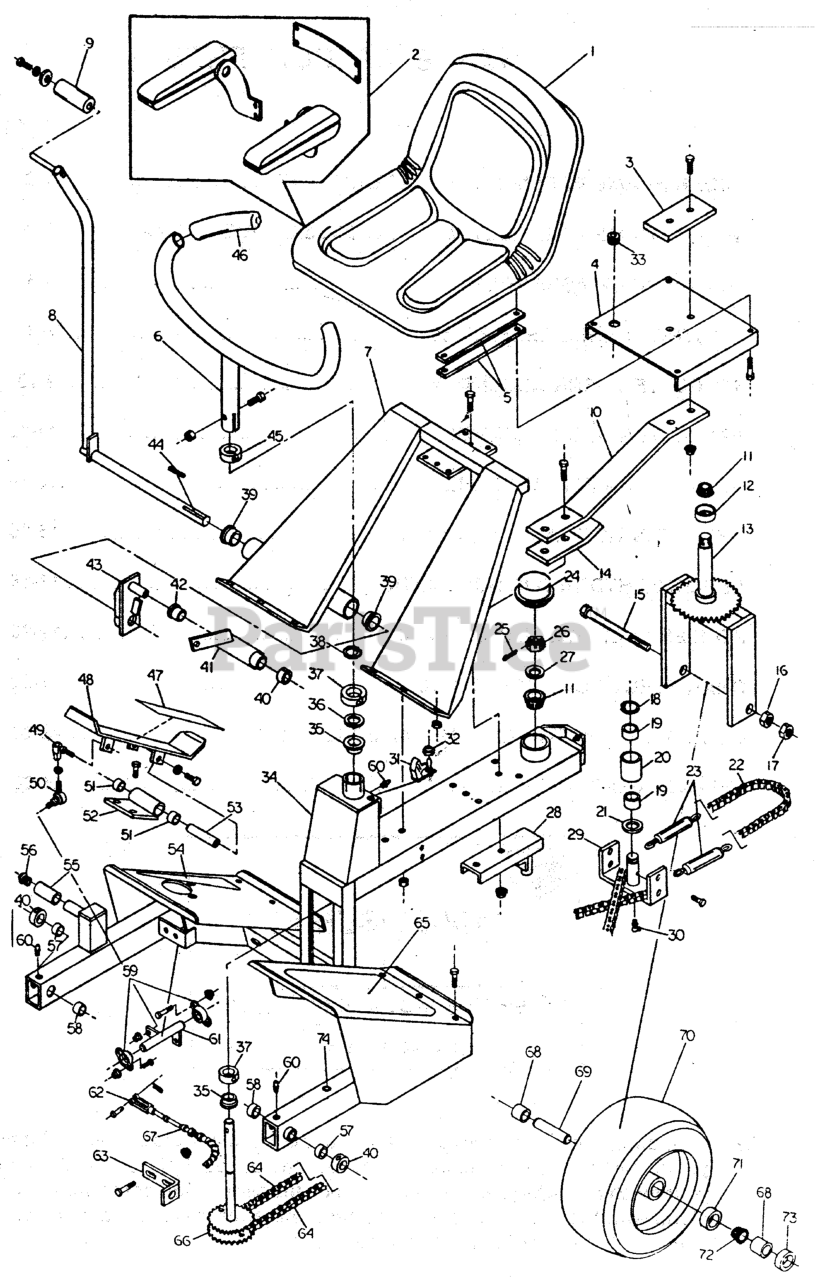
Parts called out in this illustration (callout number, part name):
2	Arm Rest Kit
2	Arm Rest (Left/Right Interchangeable)
3	SUPPORT, Seat Plate
4	Seat Plate
5	Seat Plate Spacer
6	STEERING HANDLE
7	Rider Frame Support
8	LIFT HANDLE
9	Plastic Handle
10	SEAT SPRING
11	BEARING, Tapered Roller
12	BEARING CUP
13	MOUNT, Steering Tire
14	SUPPORT, Seat Spring
15	BOLT, 5/8-11 x 9-1/2
16	NUT, 5/8-11 Hex
17	NUT, 5/8-11 Hex Side Lock
18	SNAP RING, External
19	BUSHING, Brass
20	CHAIN ROLLER
22	CHAIN, #40 Roller, 36 Links
23	TURNBUCKLE
24	CAP
25	PIN, COTTER, 1/8 X 1-1/4
26	NUT, 3/4-16 Hex Slotted
27	WASHER, 3/4 SAE
28	Steering Wheel Stop
29	Chain Roller Mount
30	45 Degree Grease Fitting
31	Switch Guard
31	Toggle Switch
32	Toggle Boot
33	GROMMET, 1/2"
34	Rider Frame
35	BUSHING, Flange
36	SHIM
37	COLLAR, 1-1/4" Split
38	Snap Ring
39	BUSHING, Flange
40	COLLAR, 3/4" Split
41	Over Center Bracket
42	BUSHING, Flange
43	Lift Bracket w/ Hub
44	KEY, 1/4 SQ. X 1
45	COLLAR, 1" Split
46	GRIP, Foam
47	SAFETY WALK
48	FOOT CONTROL PEDAL
49	BALL JOINT, 3/8" Female Studded
50	BALL JOINT, 3/8-24 Male, Studded
51	BUSHING
52	FOOT PEDAL PIVOT MOUNT, Complete
53	SHAFT, Pedal Pivot
54	SAFETY WALK
55	1" Heater Hose
56	End Plug
57	BUSHING, Brass
58	BUSHING
59	BEARING, Flange
60	GREASE FITTING
61	BELL CRANK
63	CABLE BRACKET
64	CHAIN, #40 Roller, 31 Links
65	SAFETY WALK
66	SHAFT, Steering Sprocket
67	CABLE, Speed Control
68	SPACER, 1.01 X 1.25 X 2.06
69	STEERING TIRE AXLE
70	WHEEL & TIRE ASSEMBLY, 18 x 7.5 x 8, White, Complete
71	BEARING CUP
72	BEARING, Tapered Roller
73	GREASE SEAL
74	GROMMET, 1/2"
